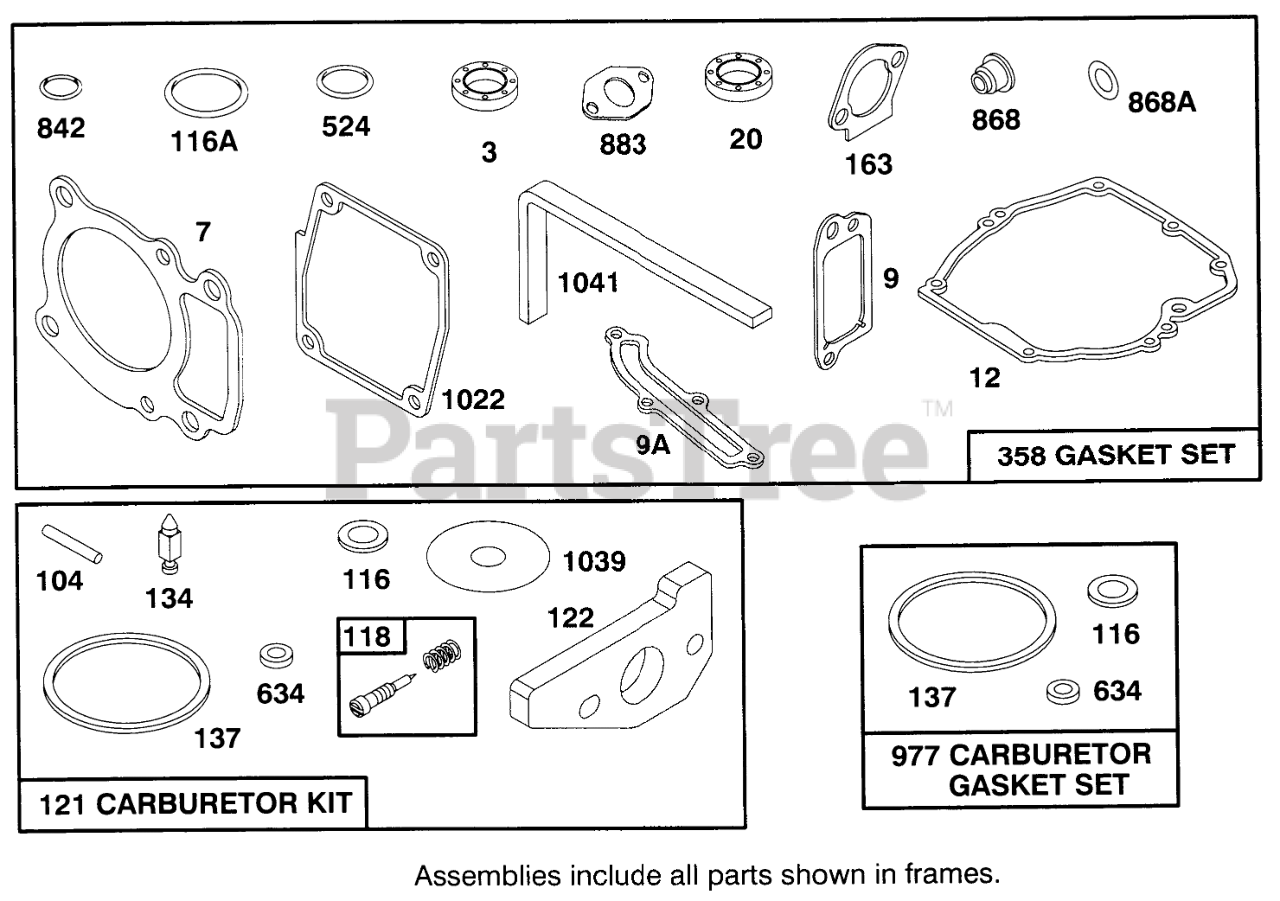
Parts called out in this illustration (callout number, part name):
3	SEAL - OIL
7	CYLINDER HEAD GASKET
9	BREATHER GASKET
9A	GASKET-BREATHER
12	ENGINE BASE GASKET
20	SEAL-OIL
104	FLOAT HINGE PIN
116	O RING SEAL
116A	SEALING GASKET
118	VALVE KIT - NEEDLE
121	CARBURATOR OVERHAUL KIT
122	ADAPTER ASSEMBLY
134	Valve-Inlet (Includes Seat)
137	FLOAT BOWL GASKET
163	AIR CLEANER GASKET
358	GASKET SET
524	O-RING
634	SEAL WASHER
842	O-RING
868	SealAssy-Valve
868A	Seal-Valve
883	EXHAUST GASKET
977	CARBURATOR GASKET SET
1022	ROCKER COVER GASKET
1039	FLOAT LIMITER
1041	SEAL - FOAM
